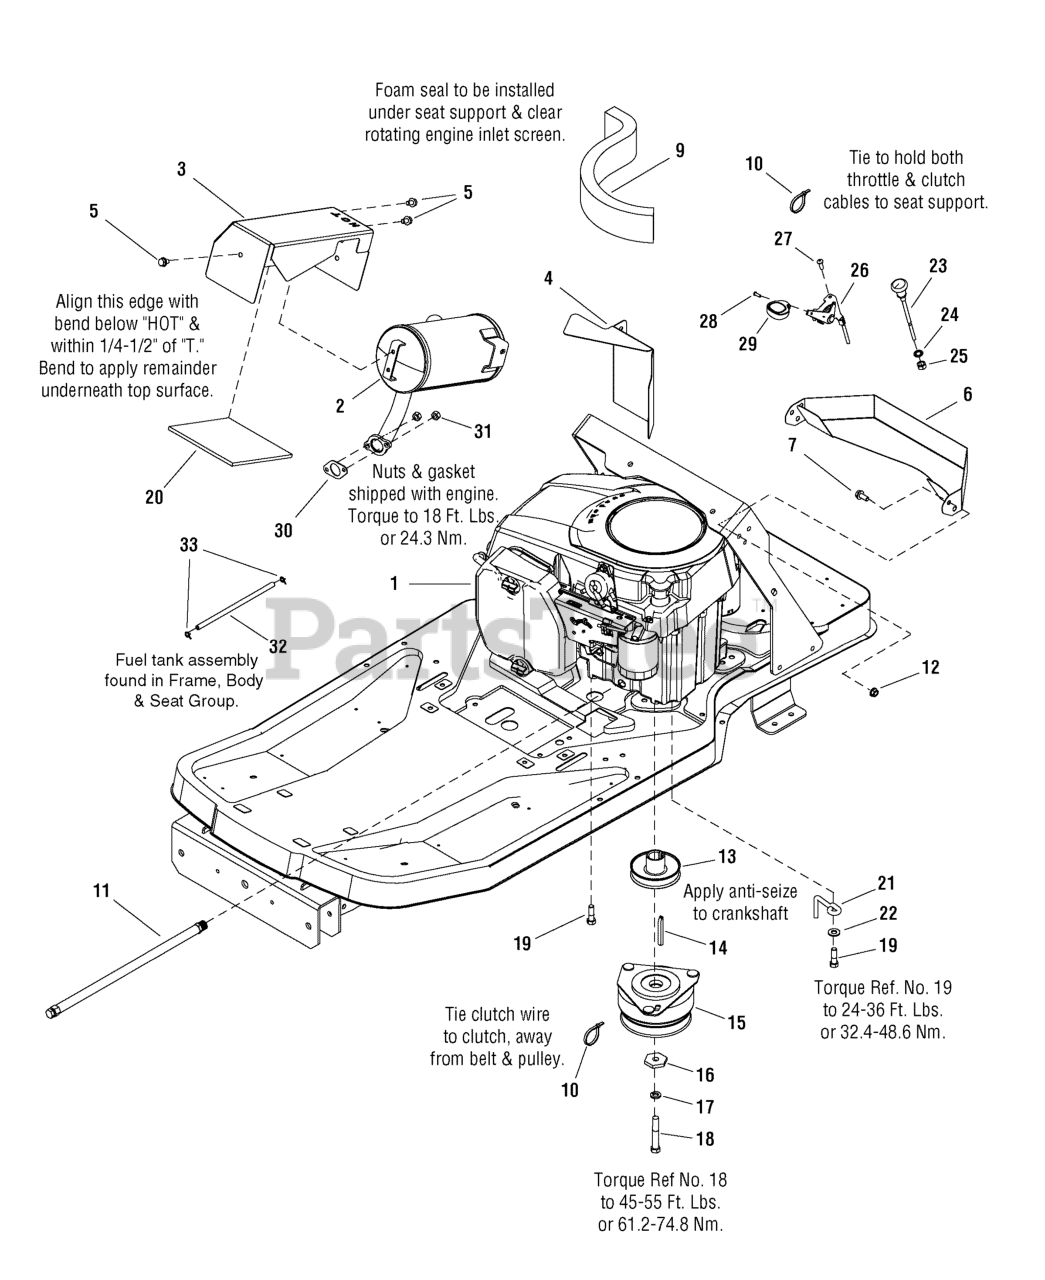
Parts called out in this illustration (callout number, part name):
1	ENGINE, 20HP Kohler Courage
2	MUFFLER, Kohler 20HP Courage ZT 7000
3	SHIELD, Muffler Top Kohler ZT 20/44
4	SHIELD, Heat Inner Kohler
5	SCREW, Hex Washer Head Taptite, 5/16-18 x 1/2
6	DUCT, Air Inlet Kohler ZT
7	SCREW, Hex Whiz Lock Flange, 5/16-18 x 3/4
9	SEAL, Foam, 1 x 2-1/2, 12" LG Curved
10	TIE, Self-Locking, .09 WD x 3.62 LG
11	HOSE, Oil Drain, 3/8 ID 16-1/2 LG
12	NUT, Hex Whiz Lock Flange, 5/16-18
13	PULLEY, 3.74 OD x 1.003 ID x 1.88 LG
14	KEY, Hi-Pro, 1/4 x 2-1/2
15	CLUTCH, #504586, Electric, Ogura JD-11
16	WASHER, Hex, .453 ID x 1-1/2 A/F 1/4 TH
17	LOCKWASHER, Spring
18	CAPSCREW, Hex Head, 7/16-20 x 2-3/4, G5
19	SCREW, Hex Washer Head Taptite, 3/8-16 x 1-1/4
20	INSULATION, Ceramic Fibers
21	RETAINER, Clutch
22	WASHER, 3/8
23	CHOKE, Cable
24	WASHER, Lock Internal Tooth, 3/8
25	NUT, Hex Head, 3/8
26	CONTROL, Throttle
27	SCREW, Pan Head Torx Taptite, 1/4-20 x 5/8
28	SCREW, Pan Head Combo Taptite, #10-16 x 3/4
29	KNOB, Plastic
30	GASKET, Muffler
31	NUT, Muffler
32	HOSE, Fuel, 11.5"
33	CLAMP, Hose
